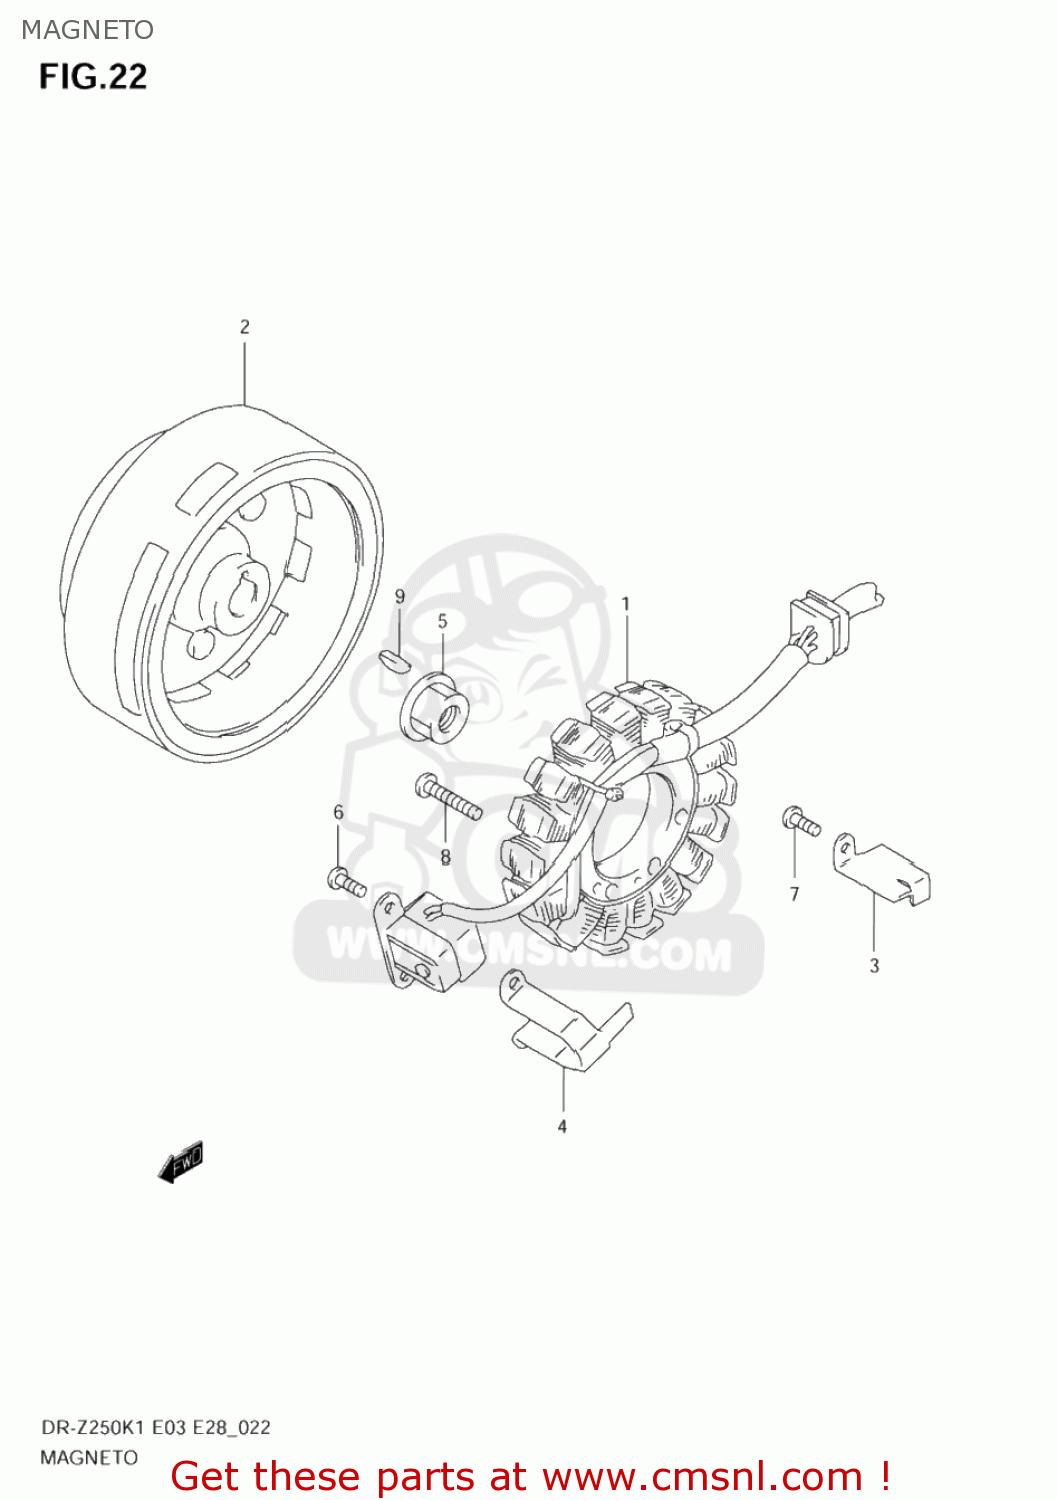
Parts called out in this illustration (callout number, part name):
1	STARTER ASSY
2	ROTOR ASSY
3	CLAMP,MAGNETO LEAD
4	CLAMP,MAGNETO LEAD WIRE
5	NUT
6	SCREW
7	SCREW
8	SCREW
9	KEY
